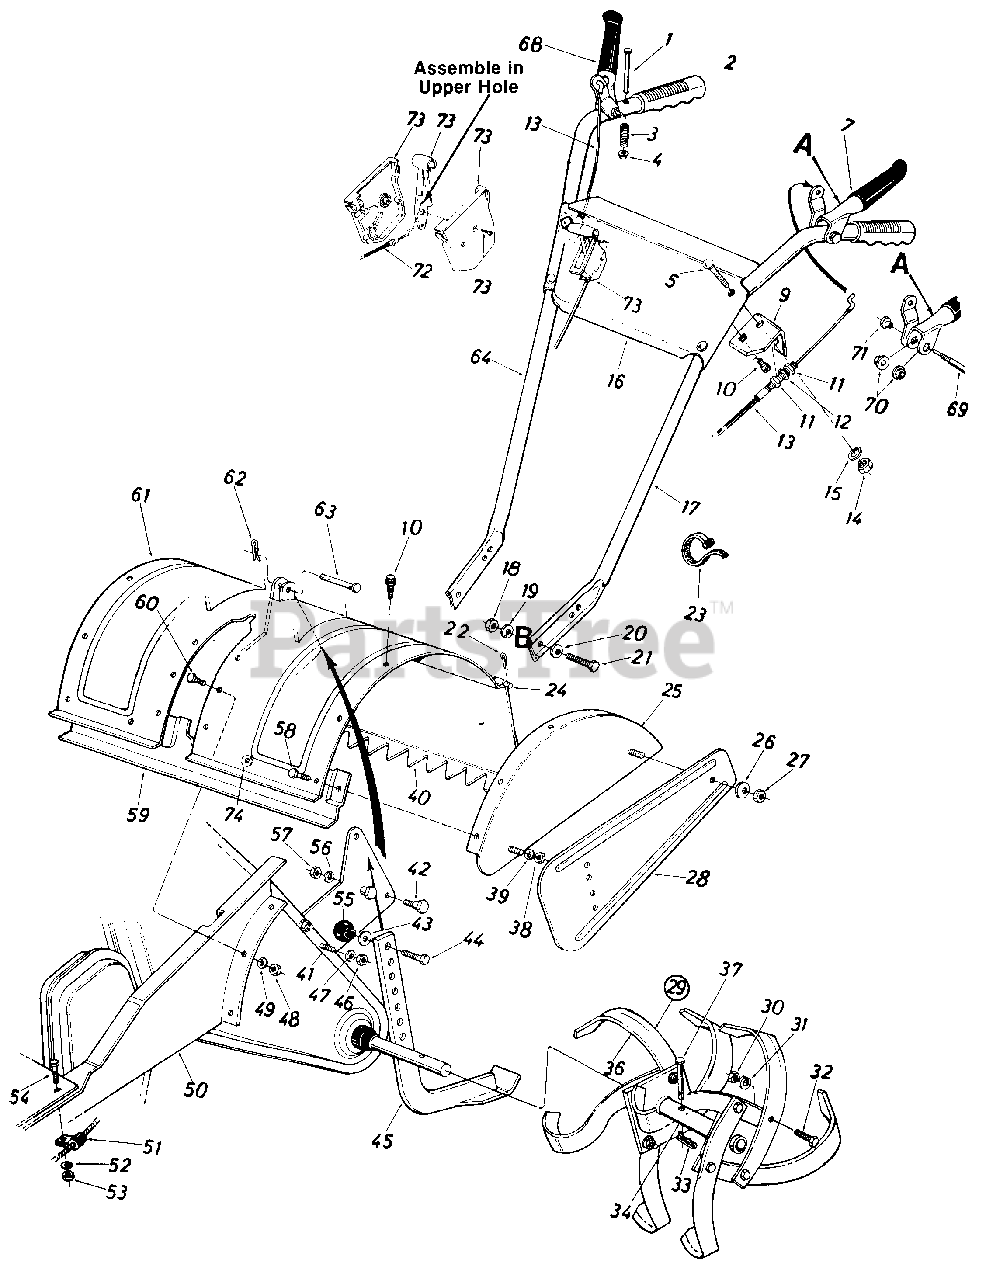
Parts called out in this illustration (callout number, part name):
1	Clevis Pin 1/4" Dia. x 2.25"
2	Grip
3	Compression Spring .33" O.D. x 1.2" Lg.
4	Cap Speed Nut 1/4" Rod
5	Carr. Bolt 5/16-18 x 1.75"
7	Clutch Grip Ass'y. L.H.
9	Clutch Cable Bracket
10	Hex Wash. S-Tap Scr. 5/16-18 x .62" Lg.
11	Hex Nut 5/16-24 Thd.
12	L-Wash. 5/16" I.D
13	Clutch Control Cable
14	Hex Nut 5/16-18 Thd.
15	L-Wash. 5/16" I.D.
16	Handle Panel
19	L-Wash. 3/8" I.D.
20	Bell-Wash. 3/8" I.D.
21	Hex Bolt 3/8-16 x 1.00" Lg.
22	Cotter Pin 3/32" Dia. x 3/4'
23	Cable Tie
24	Tiller Flap Rod
27	Hex Nut 5/16-18 Thd.
30	Hex Nut 3/8-24 Thd.
31	L-Wash. 3/8" I.D.
32	Hex Bolt 3/8-24 x 1.25" Lg.
33	Hairpin Cotter
34	Tine Adapter Ass'y.
38	Hex Nut 5/16-18 Thd.
39	L-Wash. 5/16" I.D.*
40	Tine Shield Flap
41	Hex Bolt 5/16-18 x 1.0" Lg.
42	Shld. Bolt 1/2" Dia. x .426"
43	Fl-Wash. 3/8" I.D. x 5/8" O.D.
44	Hex Bolt 3/8-16 x 3/4" Lg.
46	Hex Nut 5/16-18 Thd.
47	L-Wash. 5/16" I.D.
48	Hex Nut 5/16-18 Thd.
49	L-Wash. 5/16" I.D.
52	L-Wash. 5/16" I.D.
53	Hex Nut 5/16-18 Thd.
54	Hex Bolt 5/16-18 x 314" Lg.
55	Ball Knob 1-1/4" Dia. x 3/8-16 Thd.
56	L-Wash. 3/8" I.D.
57	Hex Nut 3/8-16 Thd.
58	Hex Bolt 5/16-18 x .75" Lg.
59	Bracket Reinforcement
60	Hex Bolt 5/16-18 x .75" Lg.
61	Tine Shield Assy.
62	Hairpin Cotter
63	Clevis Pin 3/8 Dia.
69	Shoulder Bolt .38" Dia. x 1.53" Lg.
70	Hex Flange Plastic Bearing
71	Shoulder Nut 1/4-20 Thd.
72	Throttle Control Wire
73	Throttle Control Box Ass'y.
74	Bell-Wash. 5/16" I.D.
